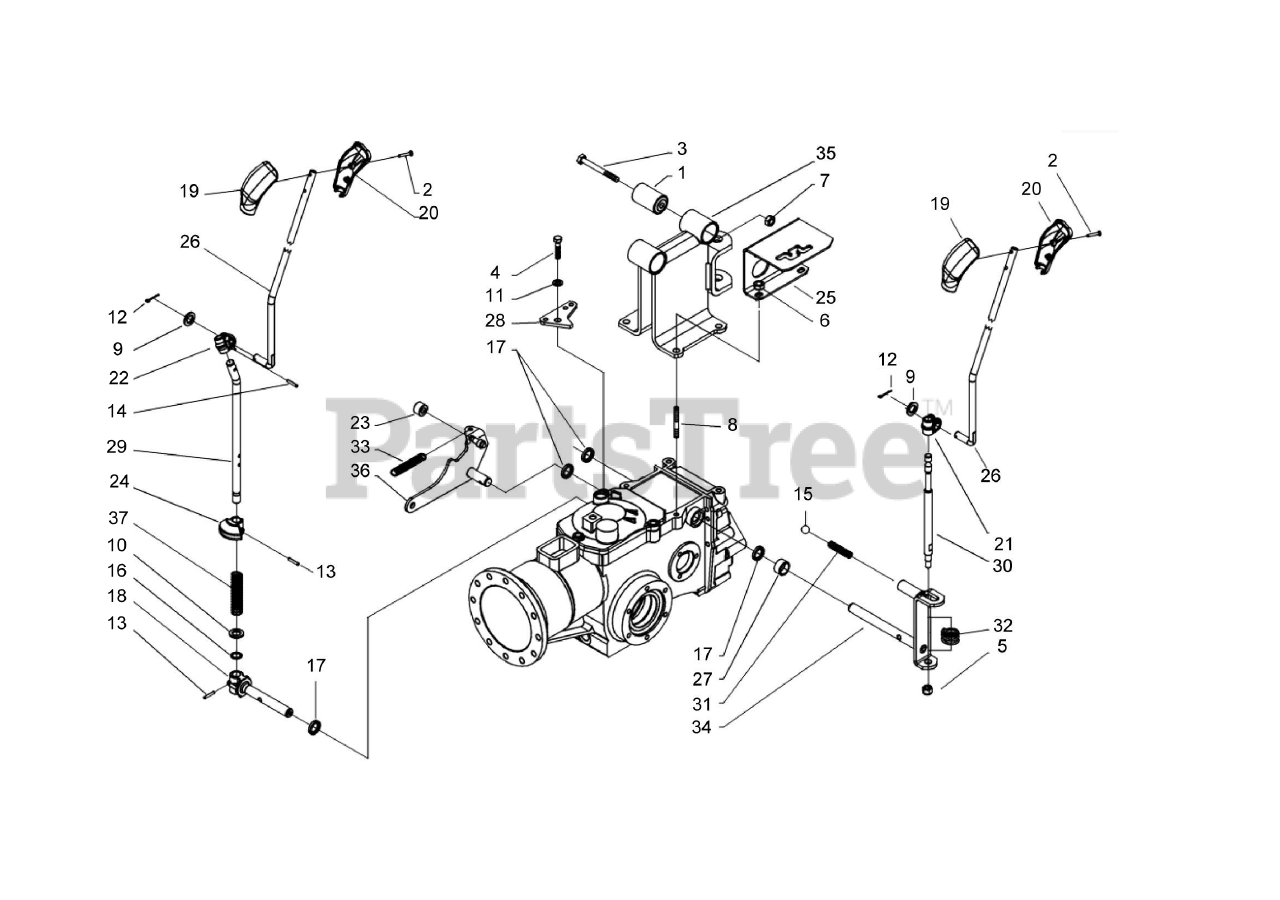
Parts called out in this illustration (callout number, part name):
1	SILENTBLOCK 10 2X30X45X4
2	SCREW 5X25 UNI 10228
3	CAPSCREW M10X75 UNI 5737-8G
4	CAPSCREW M8X30 UNI 5739-8G
5	LOCKNUT M8
6	LOCKNUT M8, FLANGED
7	LOCKNUT M10, STANDARD
8	STUD M8X38X14X20 GRADE 8
9	WASHER, FLAT M10.5X18 UNI 6592
10	WASHER, FLAT M13 UNI 1749
11	WASHER, LOCK B 8.4 DIN 137A ZINC
12	PIN, COTTER A 2X15 UNI 1336
13	PIN, SPLIT 4X20 SPIROL UNI 6876
14	PIN, SPLIT SW 4X24 SPIROL UNI 6876
15	BALL 15/32
16	0 RING 115 11.91X2.62
17	OIL SEAL M14X22X4
18	SHAFT, PTO
19	UPPER HDLE.REL.KNOB BLACK
20	LOWER HDLE.REL. KNOB
21	JOINT D 10, PLASTIC
22	ARTICULATION, PTO
23	PINS, PTO LOCKOUT
24	ARTICULATOR, PTO
25	SELECTOR, GEAR
26	PULL ROD 722
27	SPACER, LEVER
28	BRACKET ,REVERSE
29	SHIFT ARM, PTO
30	COMMAND LEVER
31	SPRING
32	SPRING, GEAR STICK
33	SPRING
34	GEAR LEVER
35	HANDLE BAR SUPPORT
36	LEVER, PTO LOCKOUT
37	SPRING DM 15X70
